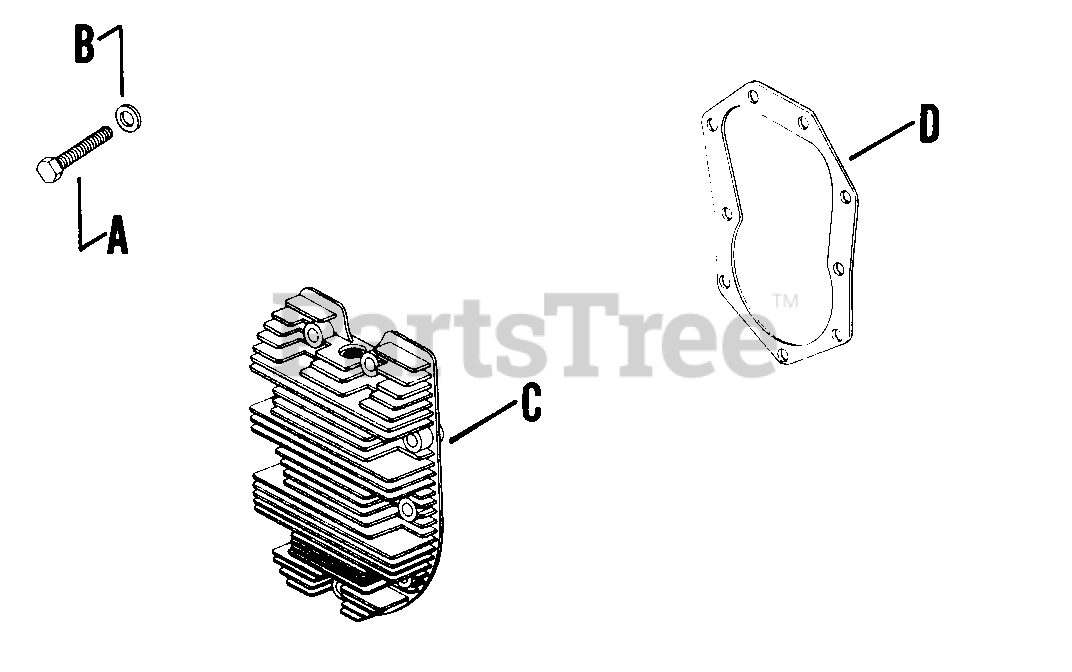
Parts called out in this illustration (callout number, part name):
A	SCREW, MACH 3/8-16X1-1/2" USE 25 086 115-S
B	WASHER, FLAT 13/32"
C	HEAD - DISCONTINUED
D	GASKET - (#DSC)
